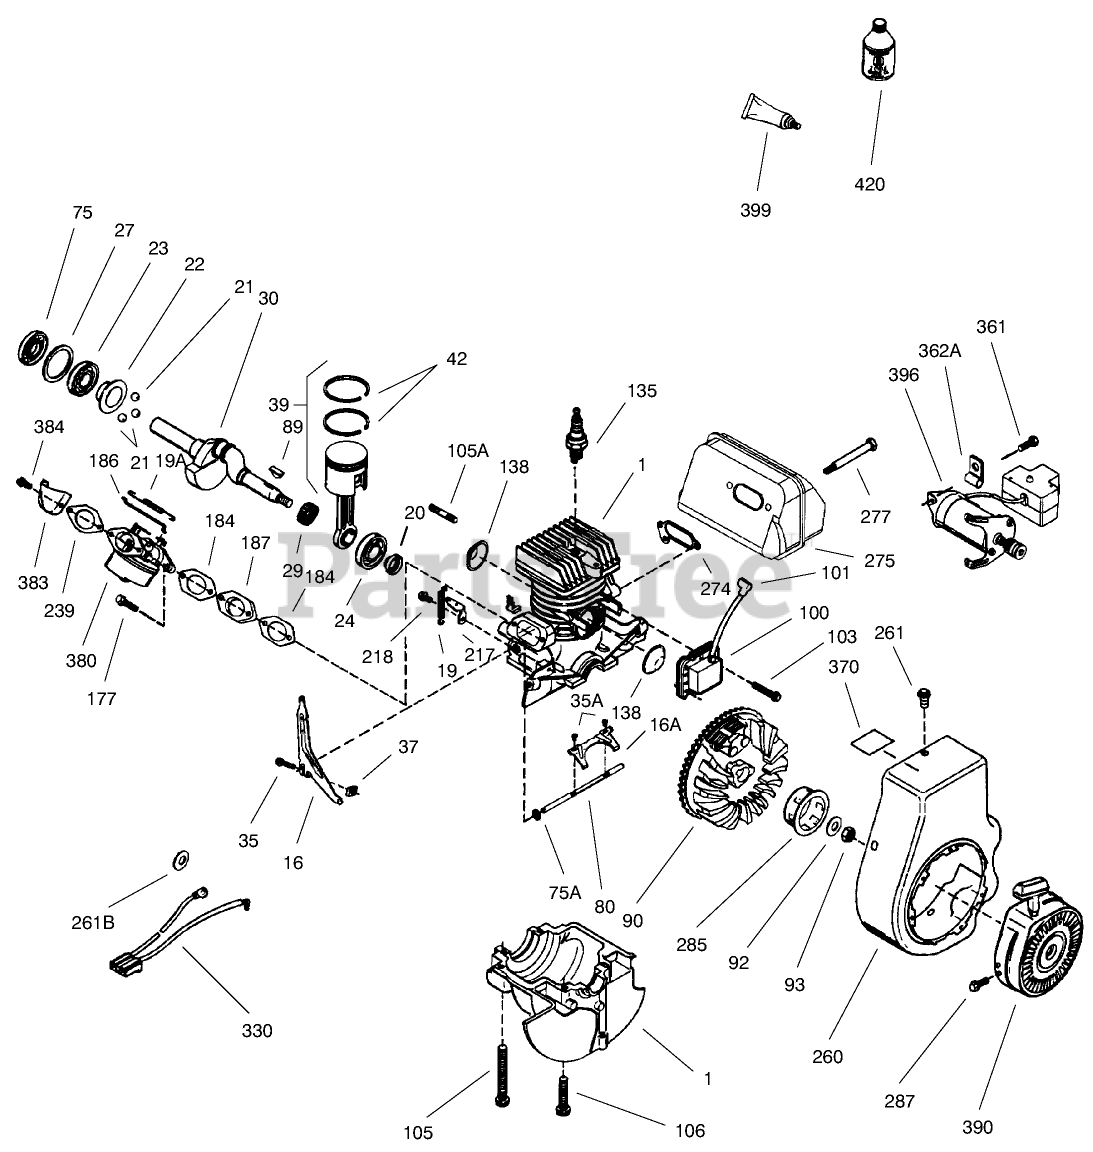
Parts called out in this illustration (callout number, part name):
1	Cylinder Ass-y (Incl. 75A, 105, 106, 138)
16	Governor Lever
16A	Governor Lever
19	Extension Spring
19A	Throttle Link Spring
20	Oil Seal
22	Ring-Slide
23	Ball Bearing
24	Ball Bearing
27	Bearing Retainer
29	Bearing-Strip
30	Crankshaft
35	Screw
35A	Screw-Shutter
37	Nut-Lock
39	Piston Rod Ass-y (Incl. 29 42)
42	Ring Set
75	Oil Seal
75A	Oil Seal
80	Governor Shaft
89	J CLIP F
90	BRACKET-BRAKE F
92	Washer-Belleville
93	Nut-Flywheel
100	Solid State
101	Cover-Spark Plug
103	Screw (T-15, 10-24 x 15/16)
105	Screw
106	Screw
135	Spark Plug-Resistor (R C J 8Y)
138	Port Cover
177	Screw (5/32 Allen, 1/4-20 x 1)
184	Gasket-Carburetor
186	Governor Link
187	Spacer
217	Control Lever
218	Screw
239	2060A77 WIZARD ROTA
260	Blower Housing
261	Screw
261B	Washer
274	Exhaust Gasket
275	Muffler
277	Screw
285	Starter Cup
287	Screw (8-32 x 21/64)
325	Clip-Wire
330	SCREW
361	Screw
362A	Extension Cord Clamp
370	Decal-Lubrication
380	Carburetor (Incl. 184 pg. 2)
383	Spit Cup
384	Screw
390	Rewind Starter Assembly (Optional)
396	Electric Starter Motor (110V)
399	Gasket Eliminator
420	2-Cycle Oil (8oz)
